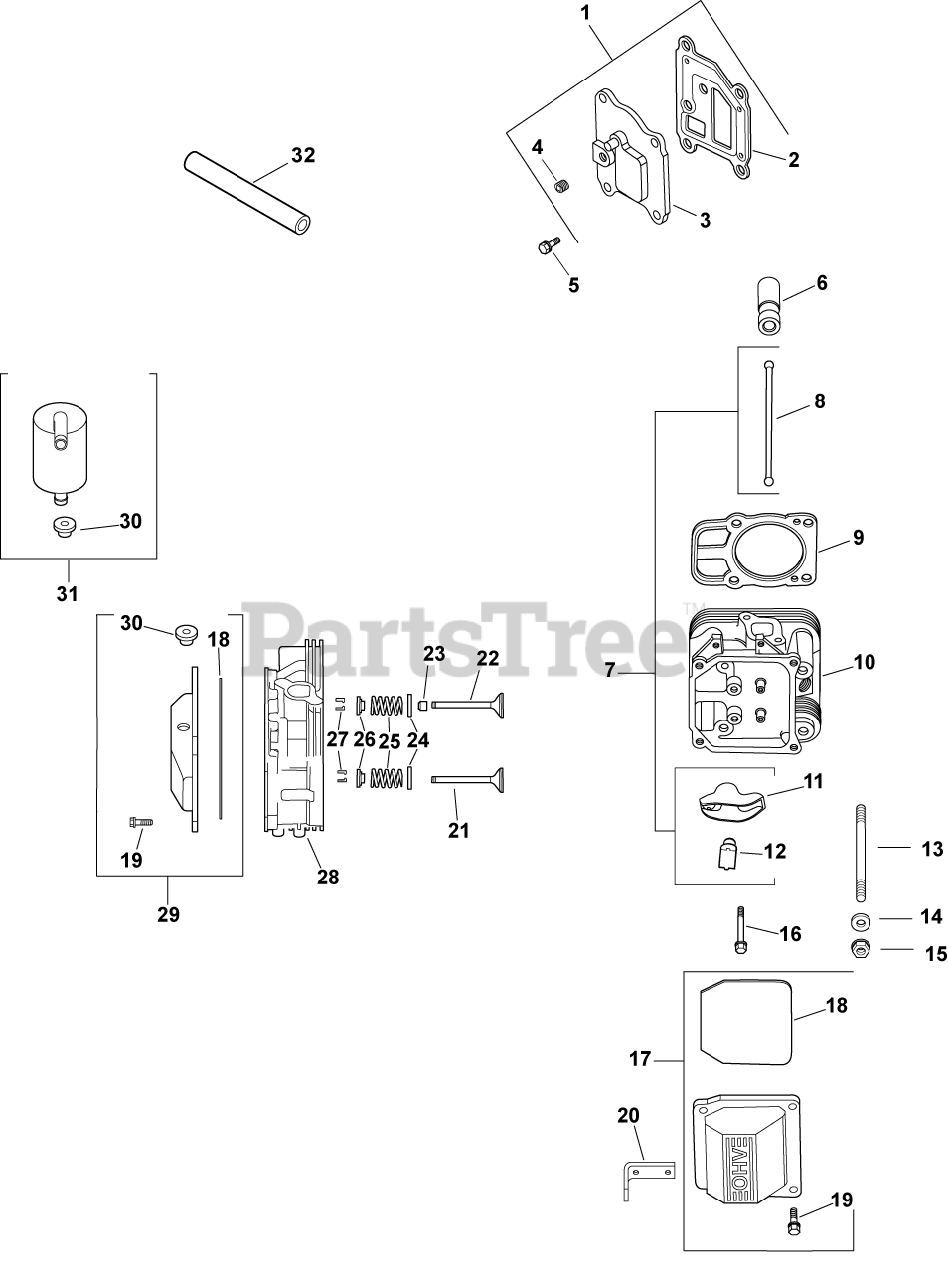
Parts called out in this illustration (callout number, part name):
1	KIT, BREATHER COVER W/GASKET
2	GASKET, BREATHER-USE 24 041 67-S
3	COVER, BREATHER -USE 24 096 125-S
4	PLUG, CTSK PIPE 1/8"
5	SCREW,FLG THD FRM M6X1.0X20-(#25086396S)
6	LIFTER, HYDRAULIC VALVE-USE 25 351 10-S
7	KIT, VALVE TRAIN
8	ROD, PUSH
9	CYL HEAD GASKET KIT-USE 24 841 04-S
10	KIT, CYLINDER HEAD #2
11	ARM, ROCKER
12	PIVOT, ROCKER ARM
13	STUD, M8X1.25
14	WASHER, FLAT 8.6 MM
15	NUT, FLG M8X1.25
16	SCREW, FLG M6X1.0X34
17	KIT, VALVE COVER-PLAIN
18	O-RING (YELLOW), VALVE COVER
19	SCREW, FLG M6X1.0X30
20	STRAP, LIFTING-USE 25 445 03-S
21	VALVE, EXHAUST (STD) - USE 32 016 01-S
22	VALVE, INTAKE (STD)
23	SEAL, VALVE STEM - (#2503214S)
24	RETAINER, SPRING
25	SPRING, VALVE
26	RETAINER, VALVE SPRING - USE 25 173 28-S
27	KIT, RETAINER
28	KIT, CYLINDER HEAD #1
29	KIT, VALVE COVER
30	GROMMET, RUBBER
31	KIT, BREATHR SEPARATR-(#24755241S)
32	HOSE, BREATHER
2401602-S	VALVE, EXHAUST (.25)
2401702-S	VALVE, INTAKE (.25)
